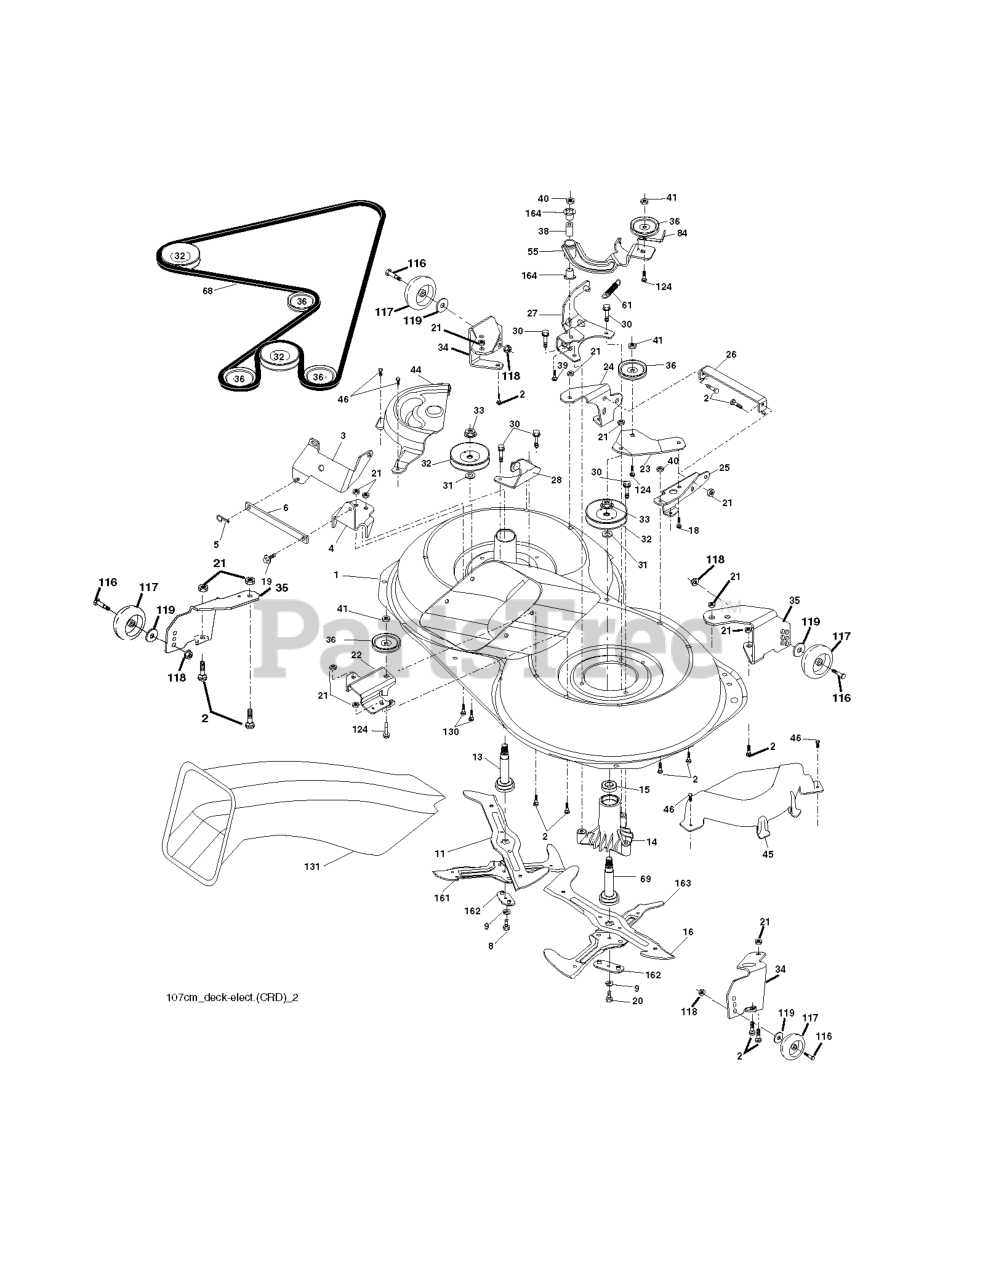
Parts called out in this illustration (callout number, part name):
1	Housing Asm. Mower 107 CRD
2	RP BOLT 5/16-18 X3/4 ZN/YEL GR
5	RETAINER-SPRNG RB
6	BAR.SWAY.92.CRD
8	BOLT.3/8-24X1.25 GR8
9	LOCKWASHER
11	BLADE.3N1.LH.CRD
13	SHAFT ASM VENT
14	HOUSING.MANDREL.VENTED (MACHD)
16	BLADE.3N1.RH.CRD
19	BOLT SHD 5/16-18
20	BOLT.3/8-24X1.25GR8. LHTHRD
21	LOCKNUT
22	BRACKET.IDLER.RR.107.CRD
25	BRACKET RF
26	SUPPORT
28	BRACKET
30	SCREW, WASHER HEAD
31	WASHER.SPACER.MANDREL
32	PULLEY.MANDREL.4.80 PD.2006
33	NUT.FLANGE.LOCK.TOP
34	BRACKET
35	BRACKET
36	PULLEY.IDLER.4.25
41	NUT LOCK FLG 3/8-16 UNC
45	COVER.MANDREL.RH.CRD
46	SCREW.1/4-20X5/8
55	ARM.IDLER.107.CRD
61	SPRING
68	HEX-BELT 107 MOWER
69	SHAFT.ASM.W/LWR.BRG.RH.THREAD
84	KEEPER, BELT IDLER
116	BOLT.SHOULDER.3/8-16X3-5/8.
117	RP WHEEL. GUAGE RALLY
118	NUT LOCK FLG 3/8-16 UNC
119	WASHER
124	BOLT.3/8-16X1.50
130	BOLT.CARR.SQNK.5/16-18UNC.X3/4
131	CHUTE BAGGER
163	BLADE.CROSS.RH.CRD.107
164	BRNG T
